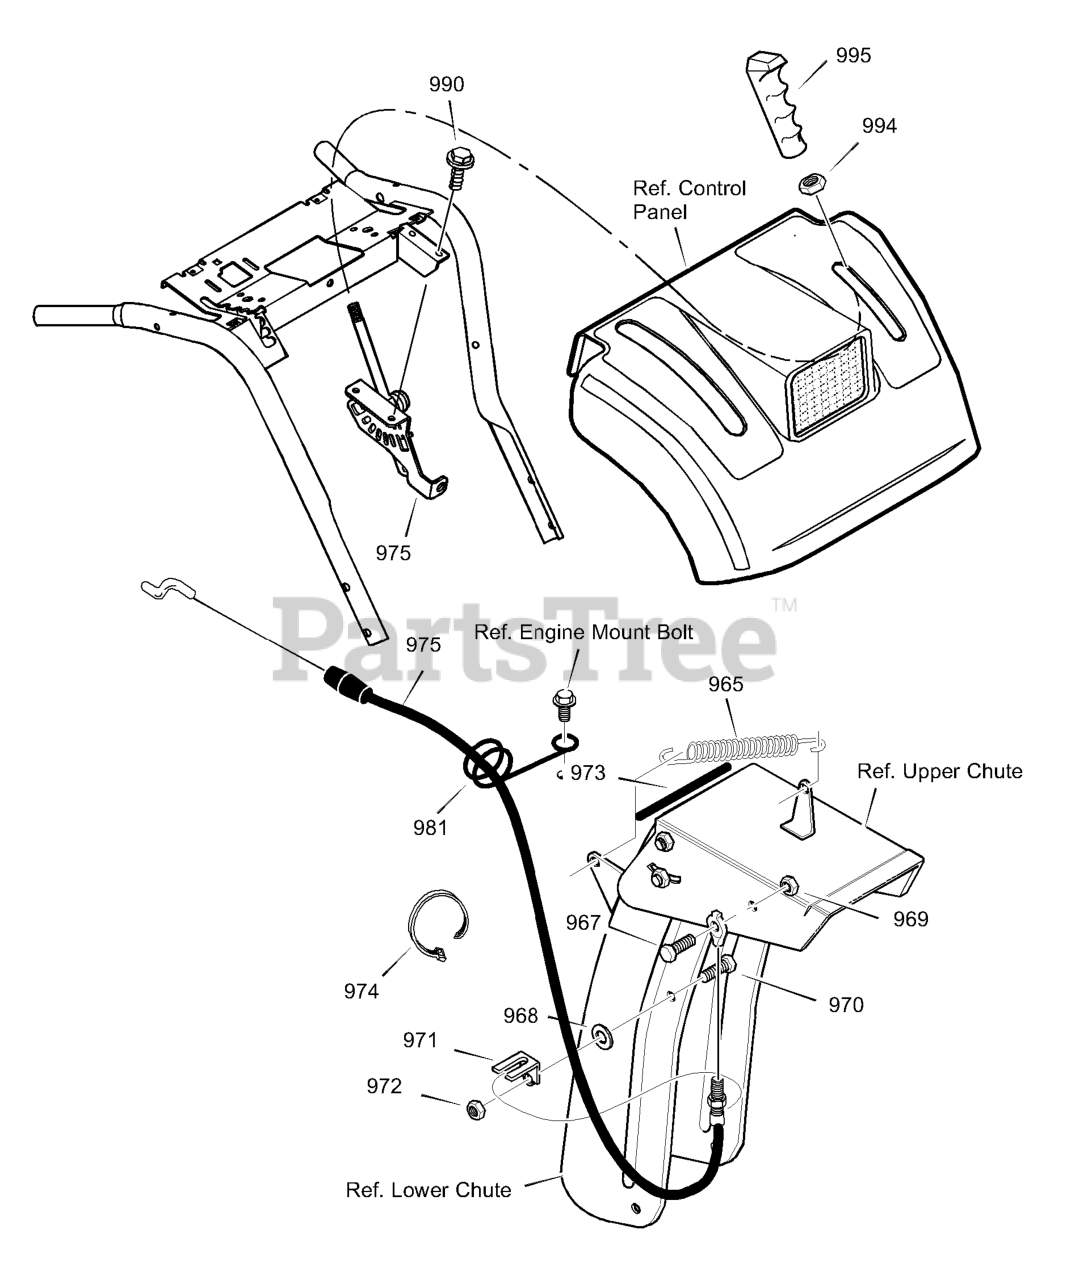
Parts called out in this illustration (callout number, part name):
965	SPRING, RETURN
967	BOLT, 5/16-18
968	WASHER, FLAT
969	NUT, 1/4-20
970	SCREW, 5/16-18 x 0.75
971	BRACKET, CABLE
972	NUT, 5/16-18
974	TIE, CABLE
975	CABLE, CONTROL
981	WIRE FORM
990	SCREW, 1/4-20 X 0.38
994	NUT, 3/8-16 HEX JAM
995	HANDLE, 3/8-16 MOLDED
